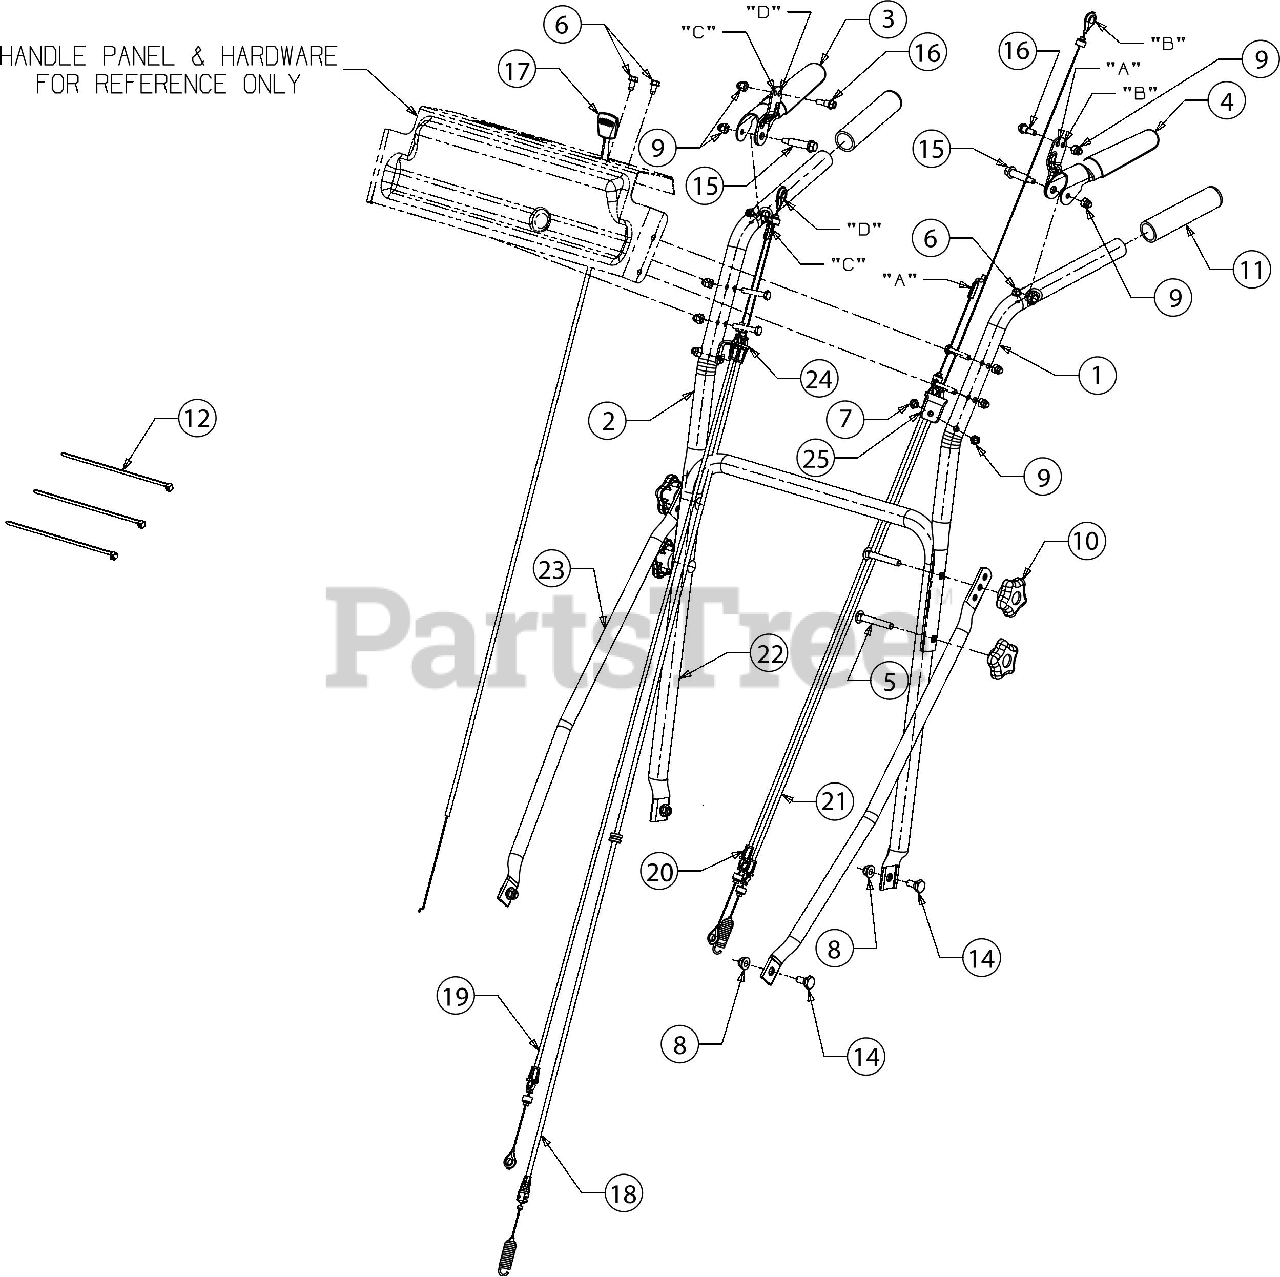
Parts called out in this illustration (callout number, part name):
1	UPPER HANDLE ASSEMBLY (LH)
2	UPPER HANDLE ASSEMBLY (RH)
3	LEVER ASSEMBLY (RH) (RED)
4	LEVER ASSEMBLY (LH) (RED)
5	SCRE W5/16-18 x 2.25 GR5
6	SCREW 1/4-20 X.500
7	SCREW 1/4-20 x 1.50 GR.5
8	FLANGE LOCK NUT 5/16-18
9	HEX ACORN NUT
10	STAR KNOB 5/16-18
12	7" CABLE TIE
14	SHOULDER SCREW .437
15	SHOULDER BOLT .375X1.285:1/4-20
16	SHOULDER SCREW .342X.335X1/4-20
17	THROTTLE/CHOKE CABLE 38" x 1.1
18	BLADE CONTROL CABLE
19	TRANSMISSION BRAKE CABLE (RH)
20	TRANSMISSION BRAKE CABLE (LH)
21	WHEEL CLUTCH CABLE
23	HANDLE ADJUSTMENT BRACE
24	CABLE BRACKET MOUNTING (RH)
25	CABLE BRACKET MOUNTING (LH)
